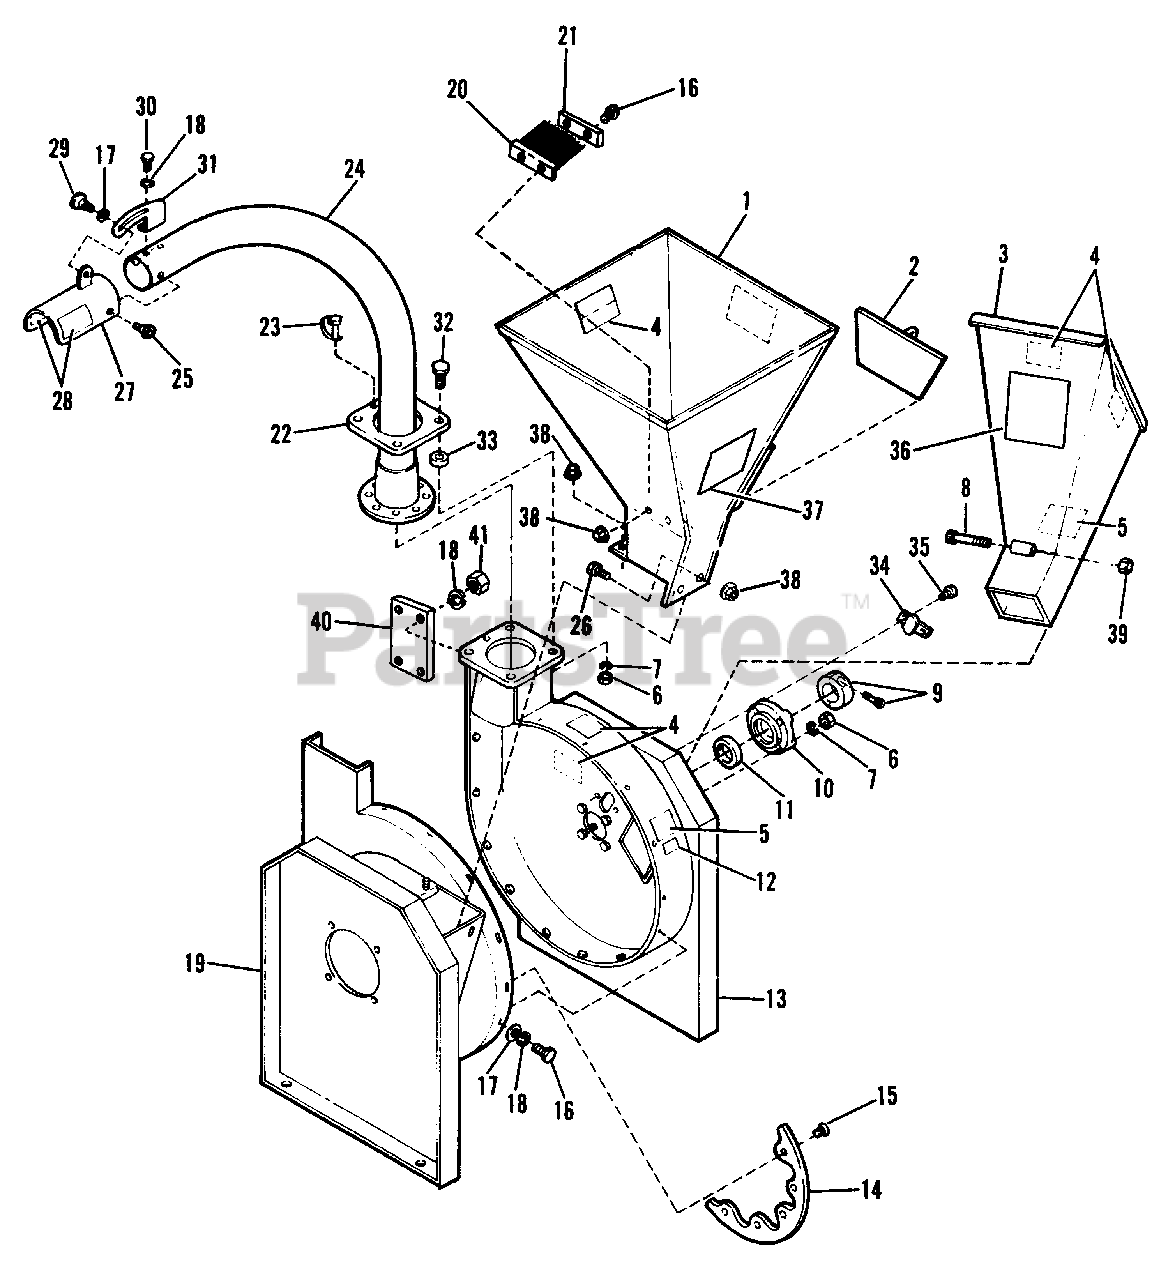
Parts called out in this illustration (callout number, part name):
1	HOPPER, Shredder
2	COVER PLATE, Vacuum
3	HOPPER, Chipper
4	DECAL, Danger, Rotating Cutters
5	DECAL, Caution
6	NUT, Hex, 3/8-16
7	LOCKWASHER, 3/8
8	CAPSCREW, Socket Hd., 3/8-16 x 4-1/2
9	COLLAR, Lock
10	BEARING, w/Race Lock & Set Screws
11	SPACER, Bearing
12	PLATE, Serial No.
13	CHIPPER HOUSING, Cone Side
14	DEFLECTOR, 20 HP
15	SCREW, Flat Hd., 5/16-18 x 5/8 (Apply Loctite)
16	CAPSCREW, 5/16-18 x 3/4
17	WASHER, 5/16
18	LOCKWASHER, 5/16
19	CHIPPER HOUSING, Drive Side
20	GUARD, Hopper
22	CLAMP, Discharge
24	DISCHARGE TUBE
25	BOLT, Shoulder, Socket Hd., 5/16-18 x 1/2
26	CARRIAGE BOLT, 3/8-16 x 1
27	DEFLECTOR, Discharge Tube
28	DECAL, Warning
29	WING NUT, 516-18
30	CAPSCREW, 5/16-18 x 1/2
31	BRACKET, Deflector Adjusting
32	CAPSCREW, 3/8-16 x 1-1/2
33	SPACER, Discharge Tube
34	PLATE, Access
35	TAPTITE SCREW, 5/16-18 x 5/8
36	DECAL, Chipper Warning
37	DECAL, Shredder Warning
38	NUT, Hex, Flange, Whiz Lock, 5/16-18
39	NUT, Hex, Flange, Lock, 3/8-16
40	DOOR, Clear-out
41	NUT, Hex, 5/16-18
